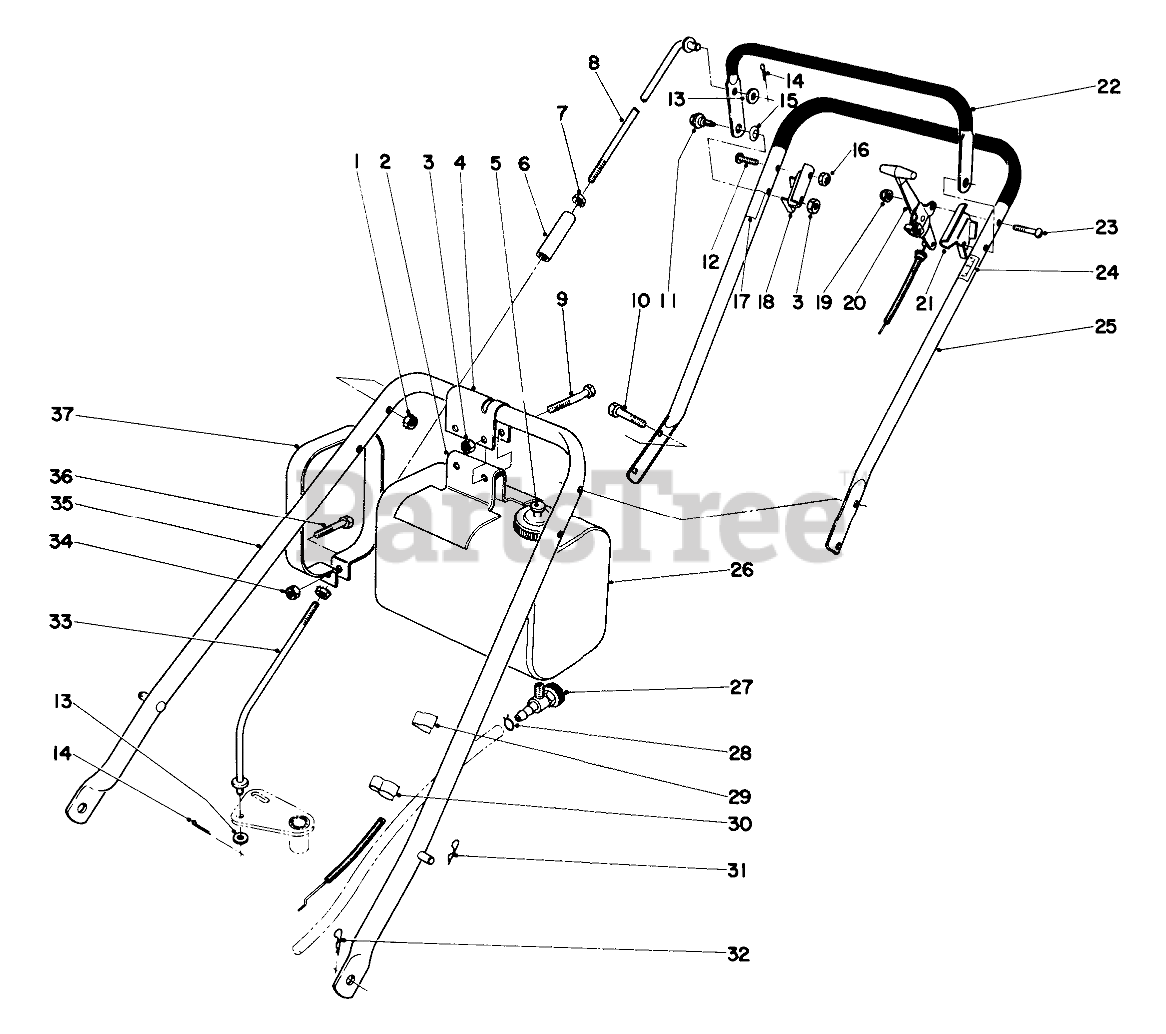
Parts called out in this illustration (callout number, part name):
1	NUT-KEPS
2	FUEL TANK BRACKET
3	Nut
4	Clamp, Fuel Tank
6	CONTROL ROD SLEEVE
7	NUT-KEPS
8	Control Rod
9	SCREW-HH
10	SCREW-HH
11	SCREW-SHOULDER
12	10-24X1-1/4 PAN HD MS
13	WASHER-PLAIN
14	PIN-COTTER
15	WASHER-SPRING
16	NUT-LOCK, NI
17	Decal
18	CONTROL BAIL BRACKET
19	NUT-LOCK, NI
20	Throttle Control
21	Bracket-Control Bail
22	Control Bail
23	10-24X1-1/8 RND HD MS
24	Decal
25	Upper Handle Assembly
26	Tank
27	.125 ID SHUTOFF VALVE
28	Clamp
29	Clamp
30	CLAMP
31	PIN-COTTER
32	PIN-COTTER, HAIR
33	CONTROL ROD
34	Nut
35	Lower Handle
36	SCREW-HH
37	TANK STRAP
